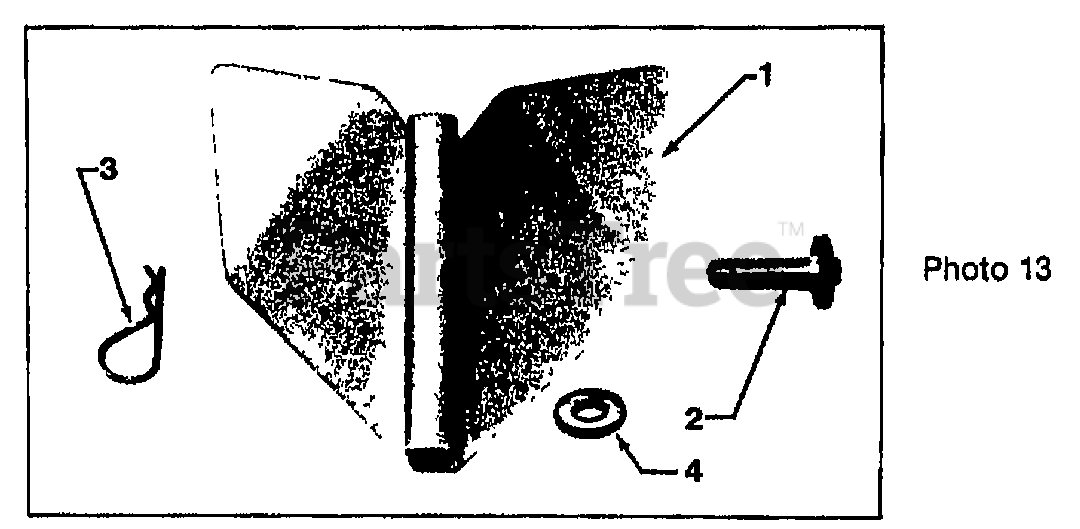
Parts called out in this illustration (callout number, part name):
1	CULTIVATOR FURROWER
2	PIN-LOCK ZP
3	PIN-HITCH ZP
4	WASHER-FLAT 3/8 SAE
